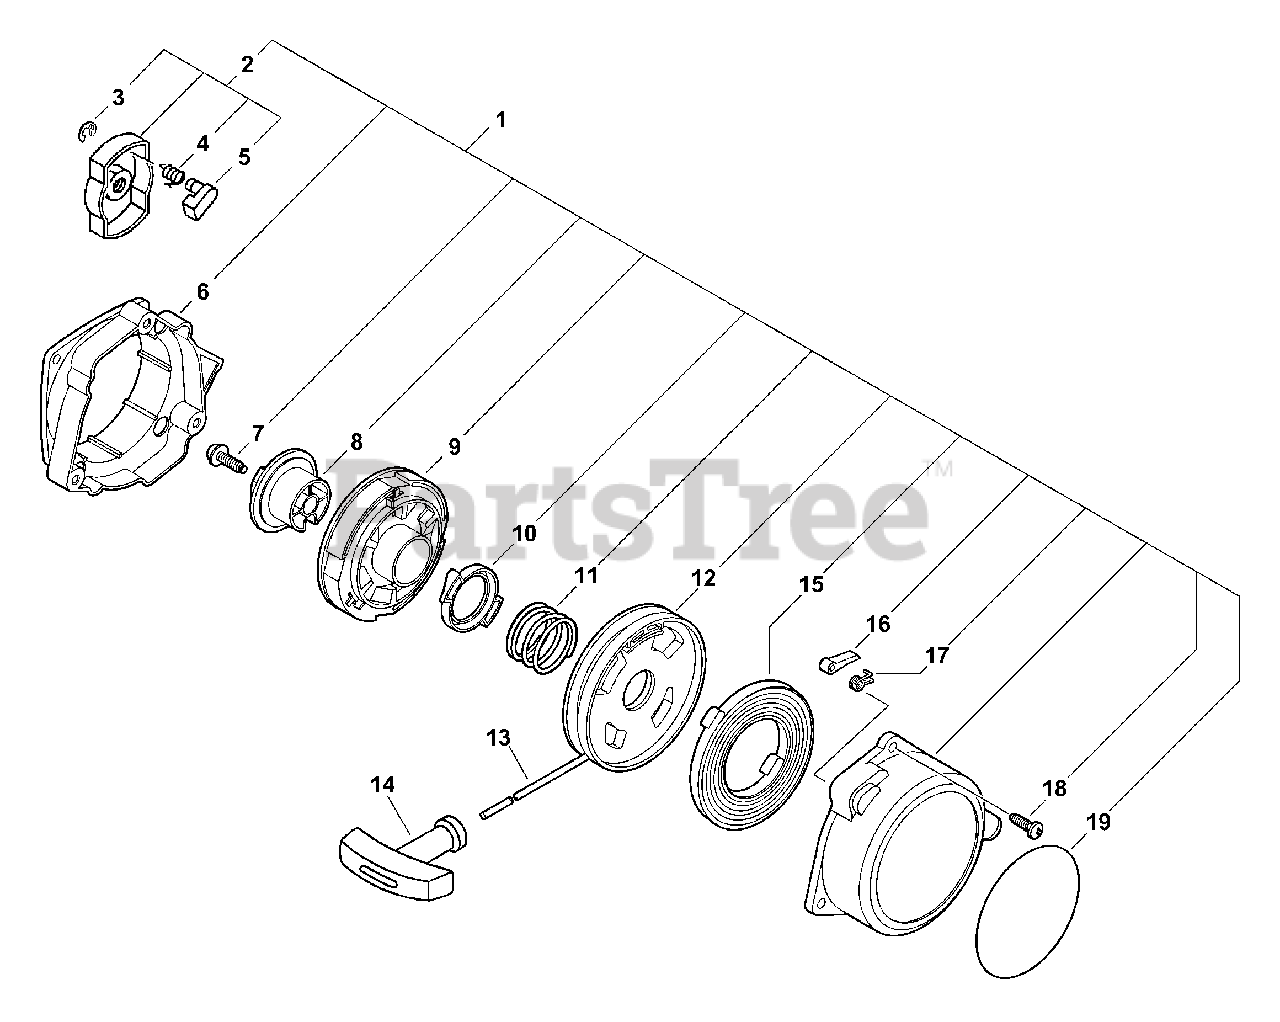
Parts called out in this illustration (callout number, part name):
1	STARTER ASSY
2	STARTER PAWL ASSY
3	RING, RETAINING - 4
4	SPRING, RETURN
5	PAWL, STARTER
8	PLATE, CAM
9	SPRING ASSY
11	SPRING, RETURN
12	REEL, ROPE
13	ROPE, STARTER - 3X800
14	GRIP, STARTER
15	SPRING, REWIND
16	PAWL, STARTER
17	SPRING, PAWL RETURN
18	SCREW - 5X20 -- TAPPING
19	LABEL - ECHO -- i
